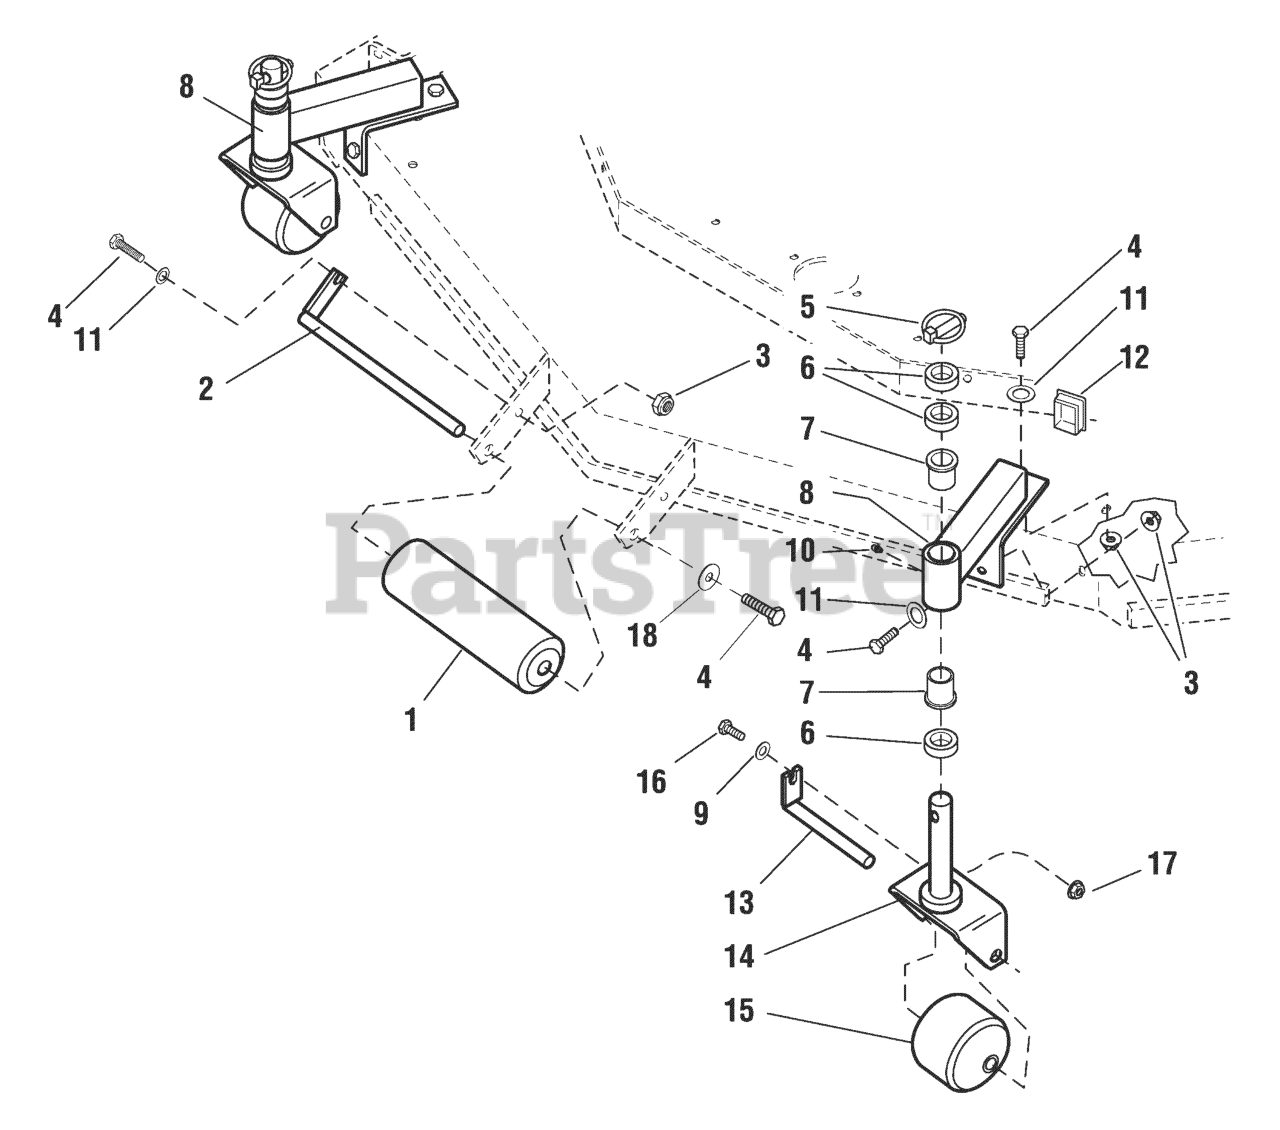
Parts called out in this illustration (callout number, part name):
1	ROLLER, DECK
3	NUT, 3/8-16 HEX NYLOCK FLANGE
4	BOLT, 3/8-16 X 1" GD5 CZ
5	PIN, LYNCH, 7/16
6	SPACER, 1.02 X 1.56 X .50
7	BUSHING, FLANGE
8	ARM, DECK CASTER WELDMENT - RED
9	WASHER, 5/16" SAE
10	GREASE FITTING, 1/4-28 STRAIGHT
11	WASHER, 3/8 SAE
12	CAP, 1-1/2 X 2 X 11GA, PLASTIC
13	WELD, CASTER ROLLER PIN - RED
14	WELD, CASTER YOKE - RED
15	ROLLER, SMALL
16	BOLT, 5/16-18 X 1" GD5 YZ
17	NUT, 5/16-18 HEX SERRATED FLANGE (SMALL)
18	WASHER, .390 X 1.50 X .109 YZ
